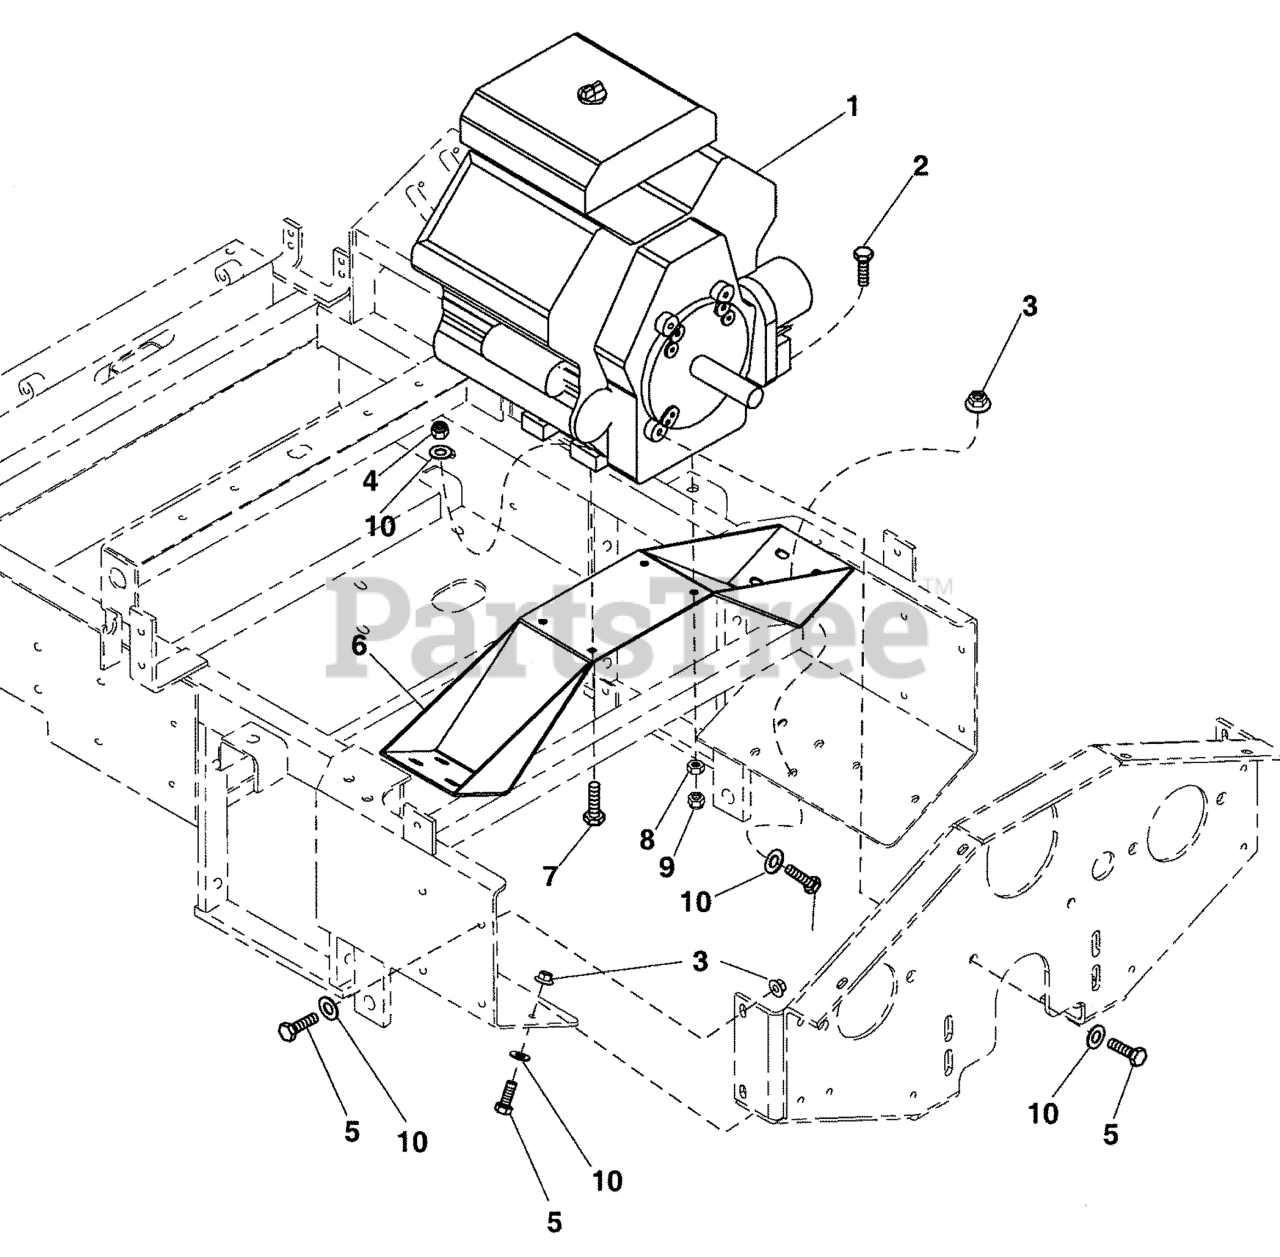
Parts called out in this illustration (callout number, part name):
1	ENGINE, Kohler
2	BOLT, 5/16-18 x 2
3	NUT, Hex, Serrated Flange, 3/8-16
4	NUT, 3/8-16 HEX NYLON LOCK
5	BOLT, 3/8-16 X 1" GD5 CZ
6	ENGINE MOUNT
7	BOLT, 3/8-16 X 2, GD5, CZ
8	NUT, 5/16-18 HEX
9	NUT, Hex, Nylon Locking, 5/16-18
10	WASHER, 3/8 SAE
